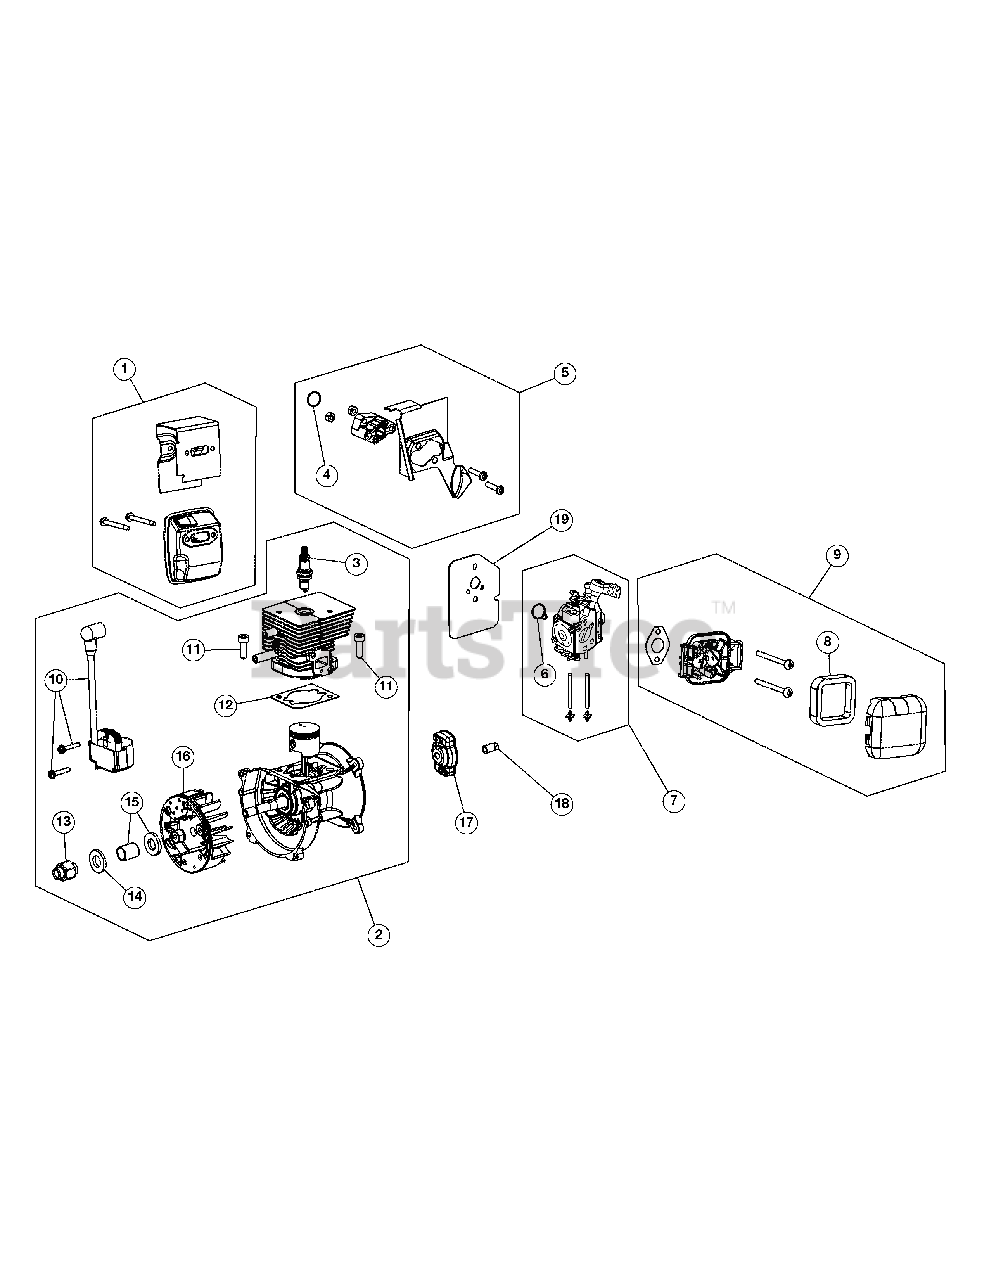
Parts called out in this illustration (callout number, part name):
1	Muffler Assembly
2	Shortblock Assembly (Incl. 3 & 10-16)
3	Spark Plug
4	Insulator O-Ring
5	Insulator Assembly (Incl. 4)
6	Carburetor Gasket
7	Carburetor Assembly (Incl. 6)
8	Air Filter
9	Aircleaner Assembly (Incl. 8)
10	Module Assembly
12	Cylinder Gasket
13	Flywheel Adapter
14	Washer
15	Bushing
16	Flywheel Assembly
17	Pawl Assembly
18	Electric Start Adapter
19	Gasket
